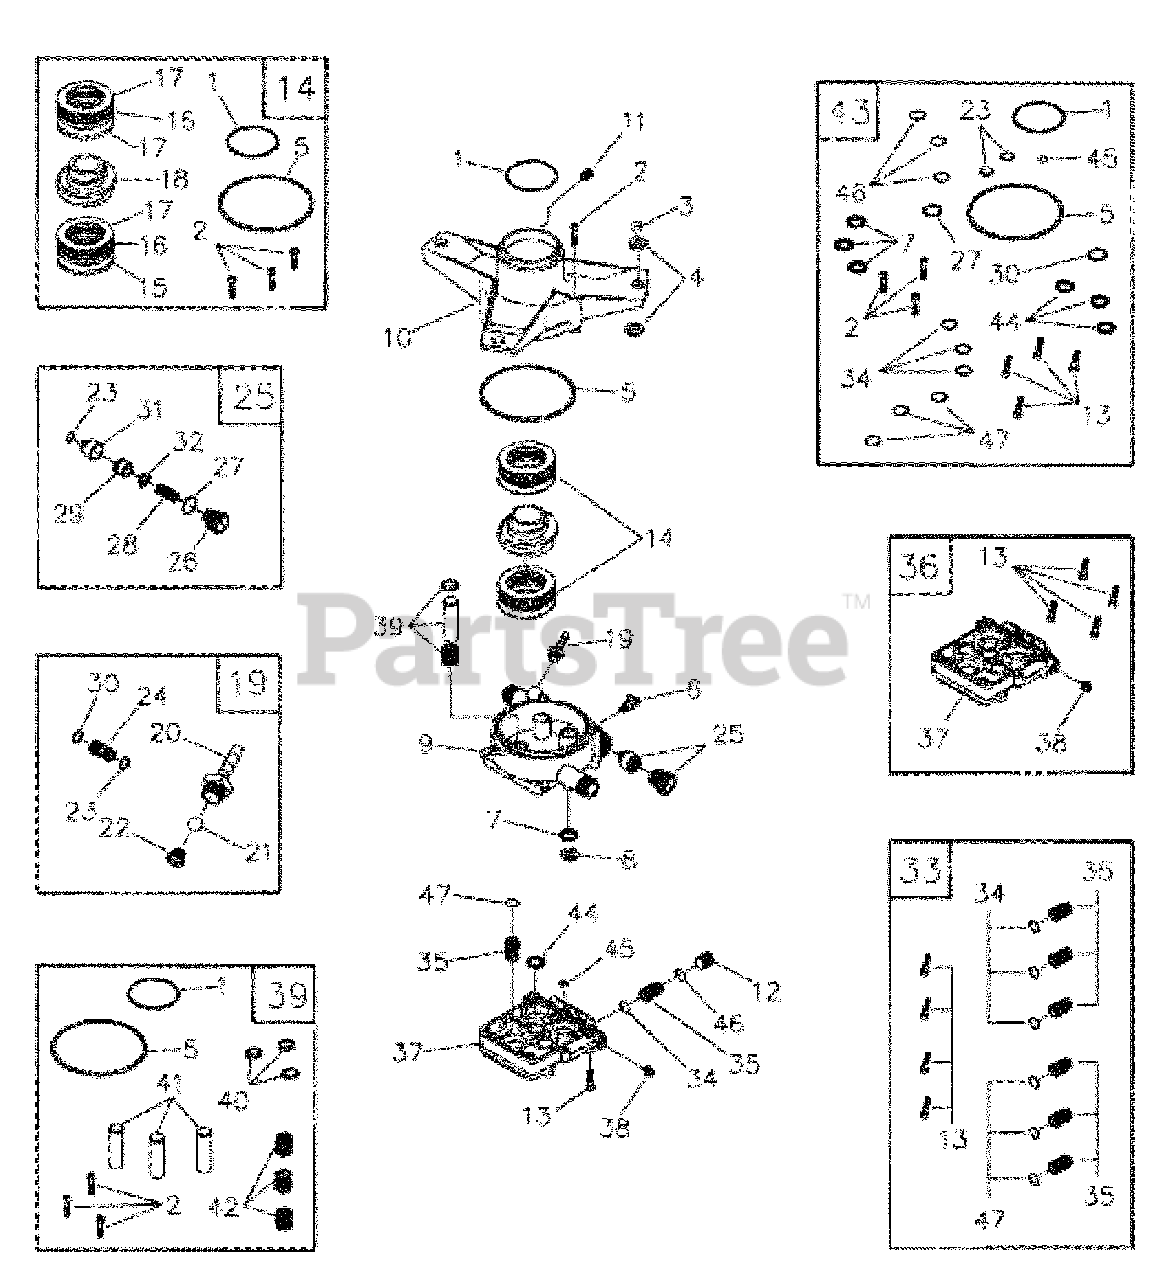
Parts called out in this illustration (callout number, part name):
1	O-RING, Engine Seal
2	SHCS, M6 - 1 x 25
3	SLEEVE, Grommet Spacer
4	BUSHING, Rubber Mount
5	O-RING, Housing Seal
6	THERMAL RELIEF, GPW-EG
7	SEAL, Oil Piston
8	SPACER, Pilot
9	HOUSING, Piston
10	ADAPTER, Engine
11	VALVE, 1/8 npt 1/5 PSI
12	CAP, Outlet Check Valve
13	SHCS, M6-1.0 x 35
14	* KIT, AXIAL CAM
15	WASHER, Brg. 36 x 65 x 6Thk
16	ASSY., Brg. Cage 45 x 65
17	WASHER, Brg. 45 x 65 x 1
18	CAM, Axial 5.6 7/8"SAE
19	* KIT, CHEM INJECT
20	FITTING, Chem Inject
21	BALL, Chem Inject
22	SPRING, Chem Inject
23	O-RING, Venturi & Seat
24	VENTURI, Chem Inject
25	* KIT, UNLOADER 2300
26	CAP, Unloader
27	O-RING, Unloader Cap
28	SPRING, Unloader
29	PISTON, Unloader
31	SEAT, Unloader
32	WASHER, 1.5mm Shim
33	* KIT, CHECK VALVES
34	O-RING, Check Valve
35	ASSY., Check Valve
36	* KIT, HEAD BRASS EG
37	HEAD, Pump
38	PLUG, 1/8-28
39	* KIT, PISTON & SPRING
40	RETAINER, Piston Spring
41	PISTON, Dia. 15 x 65
42	SPRING, Piston Return
43	* KIT, O-RING/SEAL 2300
44	SEAL, Double-Lip
45	O-RING, High Pressure Transfer
46	O-RING, Outlet CV Cap
47	O-RING, Check Valve, White
